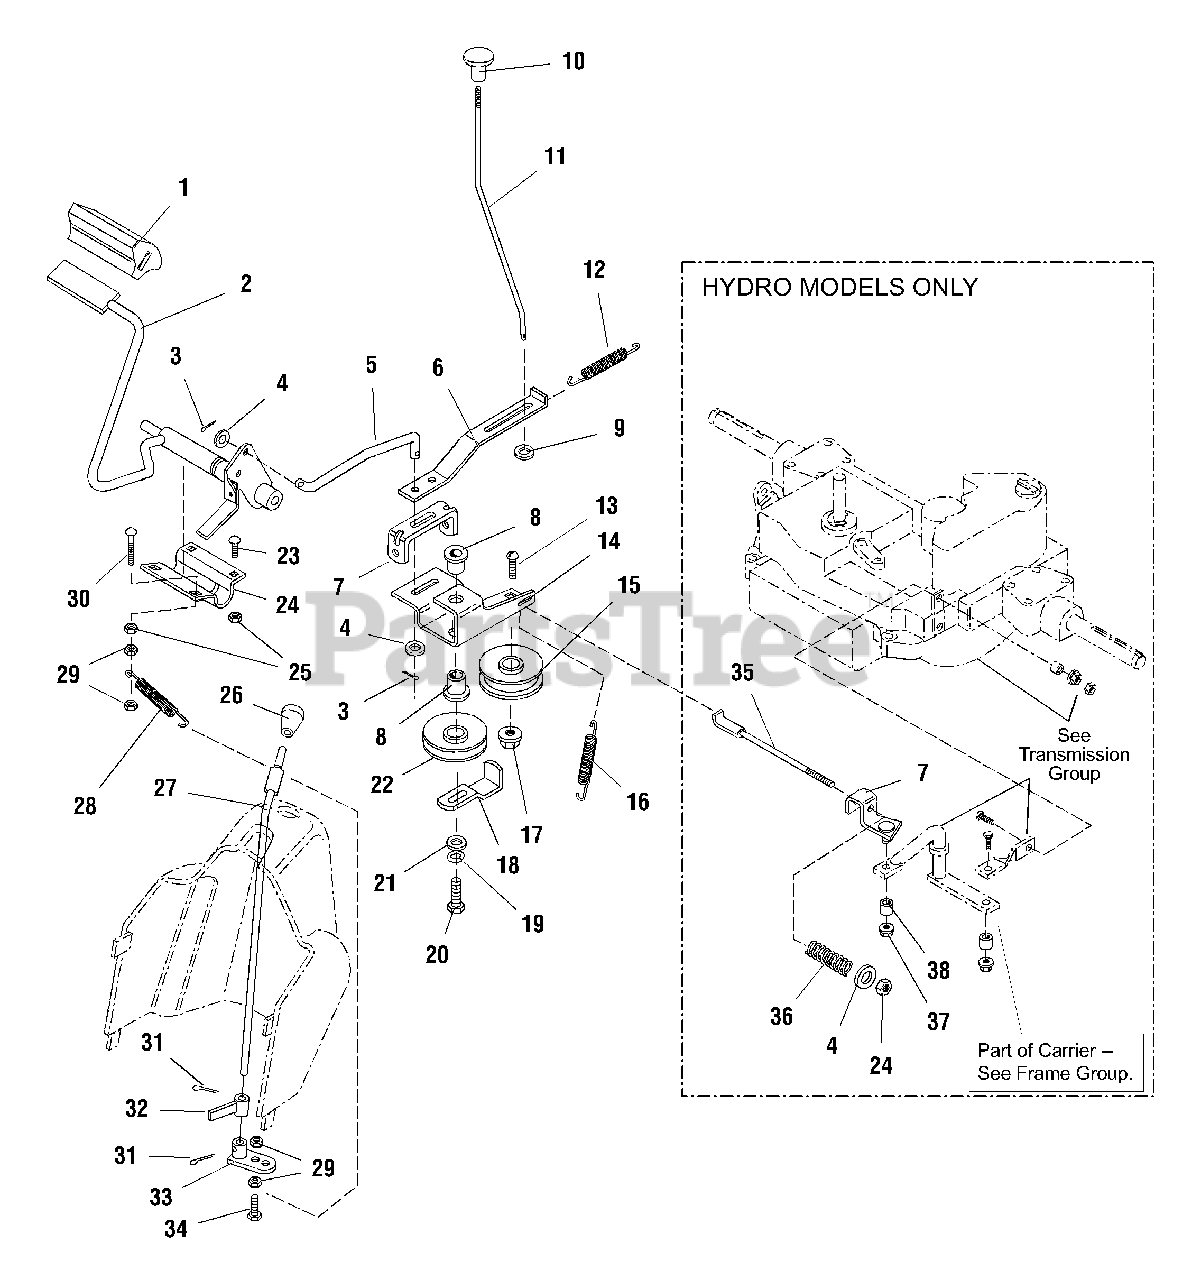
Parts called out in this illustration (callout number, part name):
1	PAD, Brake
2	FOOT PEDAL ASSEMBLY
3	PIN, Cotter, 3/32 x 3/4
3	PIN, Cotter, 1/8 x 3/4
4	WASHER, Plain, 5/16
5	ROD, Clutch
6	LEVER, Parking Brake
7	GUIDE, Brake Rod
8	BUSHING, Plastic, 5/8
9	WASHER, Plain, 1/4
10	KNOB, Plastic, Parking Brake
11	ROD, Parking Brake
12	SPRING, Parking Brake
13	CARRIAGE BOLT, 3/8-16 x 1-3/4
14	BRACKET, Idler
15	PULLEY, Backside
16	SPRING, Idler
17	NUT, Hex Flange Whiz Lock, 3/8-16
19	LOCKWASHER, 3/8
20	CAPSCREW, Hex Hd, 3/8-16 x 1-3/4
21	WASHER, Plain, 3/8
22	PULLEY, Idler, V
23	CARRIAGE BOLT, 5/16-18 x 3/4
24	CLAMP, Tube
25	NUT, Hex Nylon Lock, 5/16-18
26	KNOB, Plastic, Gear Shift
27	SHAFT, PTO Clutch
28	SPRING, Extension
29	LOCKNUT, 5/16-18
30	CARRIAGE BOLT, 5/16-18 x 1 1/2
32	HUB & BAR ASSEMBLY, PTO Clutch
33	ARM & HUB ASSEMBLY, PTO Clutch
34	CAPSCREW, 5/16-18 x 1
35	ROD, Brake
36	SPRING
37	NUT, Hex Flange Lock, 5/16-18
38	SPACER
